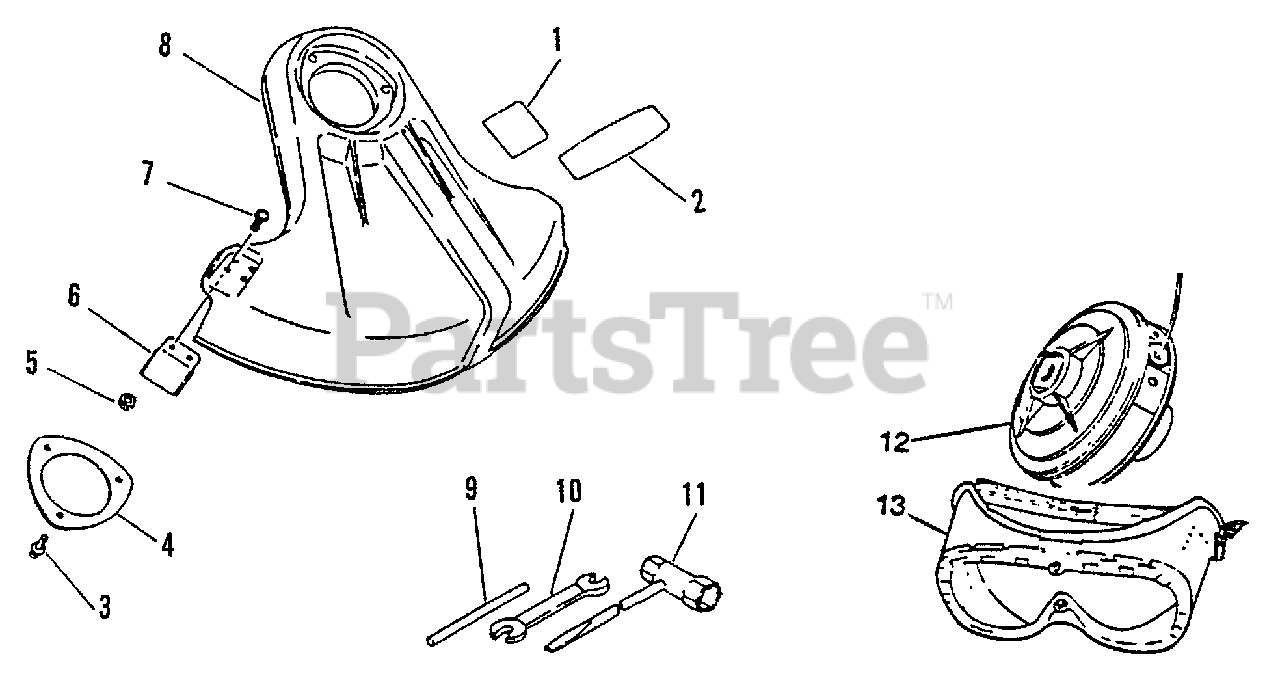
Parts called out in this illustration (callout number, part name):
1	LABEL, CAUTION
2	LABEL, ECHO
3	SCREW 5×16
4	BRACKET, SHIELD
5	NUT M5
6	CUTTER, LINE
7	SCREW 5×16
8	SHIELD
9	TOOL, LOCKING 5×120 MM
10	SPANNER 8×10
11	T-WRENCH
12	TRIMMER HEAD, SRM ECHOMATIC®
